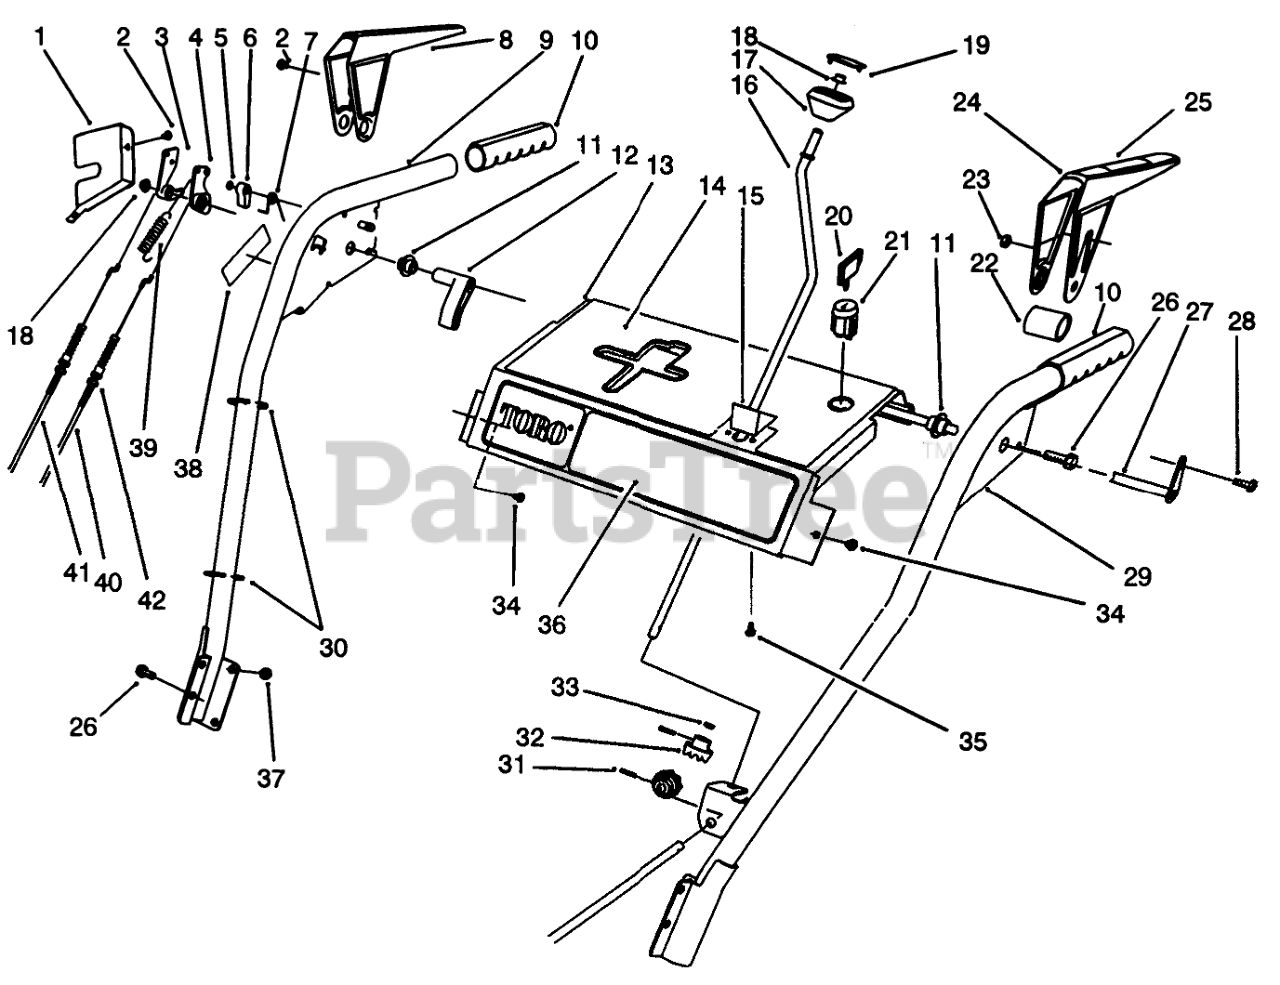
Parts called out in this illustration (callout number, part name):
1	Cover Lever Lock
2	SCREW-HH
3	TANG-LOCKING
4	CAM-RELEASE
5	E-RING-RETAINER
6	LATCH-LOCKING
7	SPRING-TORSION
8	Lever-Impeller
9	Handle-R.H.
10	GRIP-HANDLE
11	BUSHING-LEVER
12	LEVER-TRIP
13	Panel-Control
14	Decal-Panel, Top
15	PLATE-GUIDE
16	CRANK-ROD, CHUTE
17	KNOB-CONTROL, CHUTE
18	RETAINER-PUSH ON
19	COVER-KNOB
20	KEY-IGNITION
21	SWITCH
22	SPACER-LEVER, TRACTION
23	NUT-LOCK, NI
24	Lever-Traction
25	Decal-Lever
26	SCREW-HHF
27	CROSS ROD ASM
28	SCREW-HWH
29	Handle-L.H.
30	TIE-CABLE
31	PIN-SPRING
32	GEAR-UNIVERSAL
33	WASHER-RUBBER
34	SCREW-HWHTF
35	SCREW-PPH
36	DECAL - FRONT PANEL
37	NUT-LOCK, NI
38	DECAL-WARNING
39	SPRING-EXTENSION
40	CABLE-TRACTION
41	CABLE-IMPELLER
42	NUT-LOCK, NI
